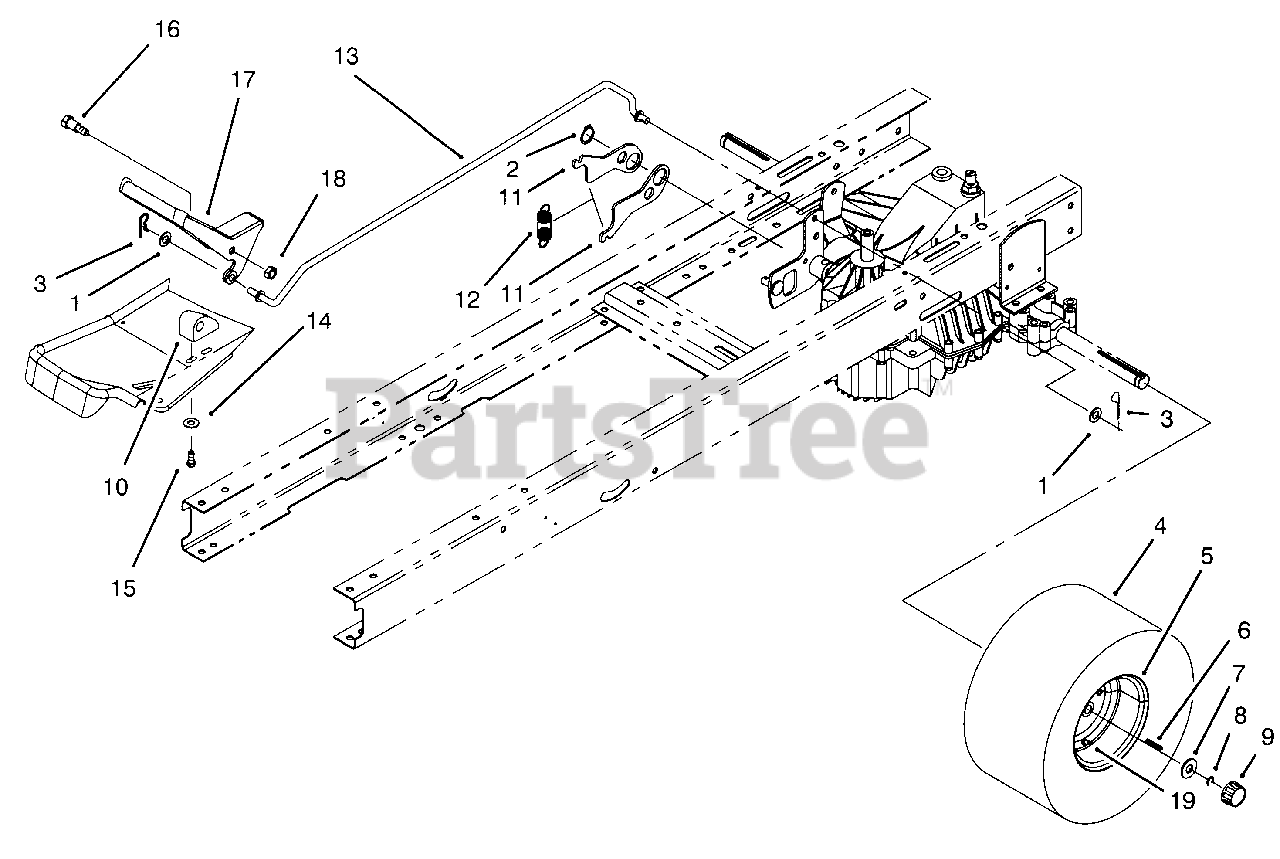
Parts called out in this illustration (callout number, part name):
1	Washer-Flat
2	Ring-External Retaining
3	Pin-Cotter
6	Key-Square
10	Block-Pivot
11	Lever-Neutral Control
12	Spring-Extension
13	Rod-Speed Control
14	Washer-Flat
15	Screw-Plastite
16	Bolt-Shoulder
17	Pedal-Speed Control
18	Nut-Lock
19	Valve Stem w/Cap
